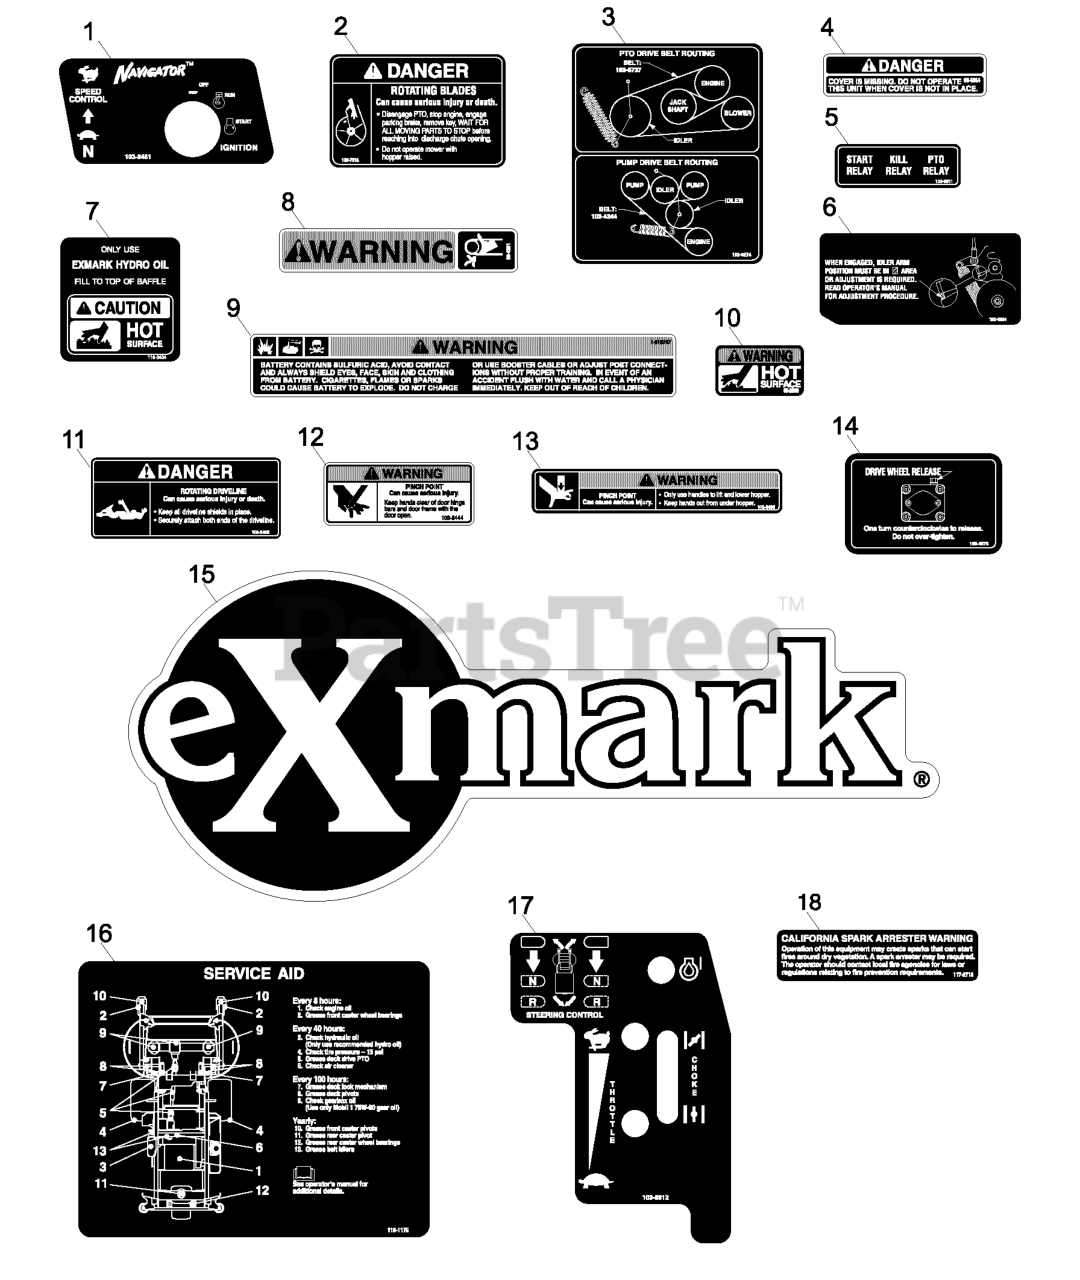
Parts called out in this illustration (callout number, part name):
1	DECAL,IGNITION/SPEED CONT
2	DECAL-DANGER IMPELLER
3	DECAL,BELT ROUTING
4	DECAL-COVER, MISSING
5	DECAL,RELAY
6	DECAL,CLUTCH ADJUSTMENT
7	DECAL-HYDRAULIC TANK
8	DECAL-WARNING
9	DECAL-BATTERY
10	DECAL-SURFACE, HOT
11	DECAL-DRIVELINE
12	DECAL-PINCH POINT
13	DECAL,PINCH POINT
14	DECAL,WHEEL MOTOR RELEASE
15	DECAL,EXMARK LOGO
16	DECAL-SERVICE AID
17	DECAL,INSTRUMENT PANEL
18	DECAL-ARRESTER, SPARK
